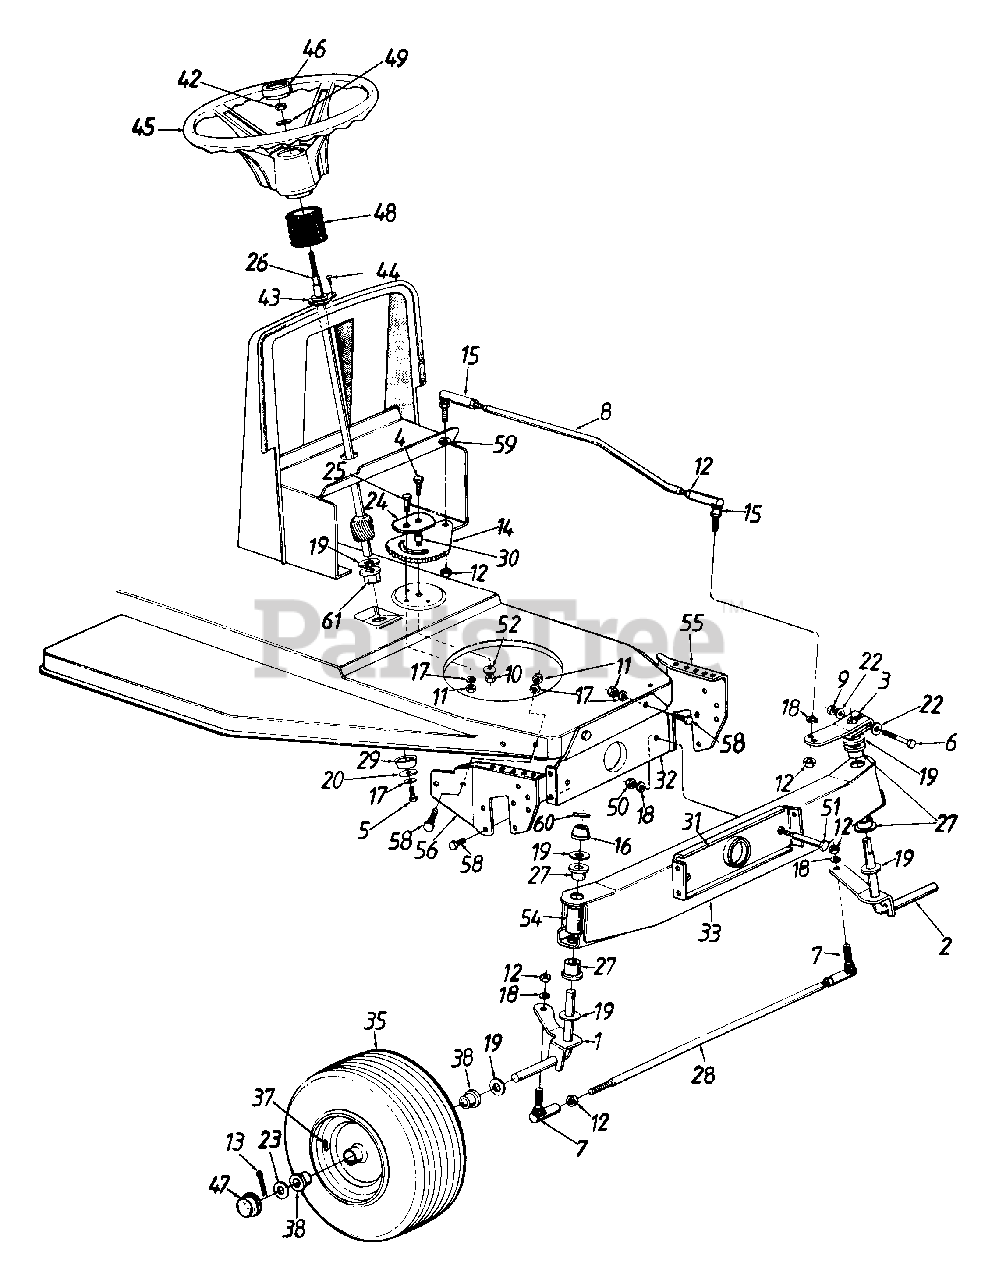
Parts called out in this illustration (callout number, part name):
1	Front Axle Ass'y.- R.H. w/Bronze Bearing
2	Front Axle Ass'y.- L.H. w/Plastic and Ball Bearing
3	Steering Arm
4	Hex Bolt 3/8-24 x 1" Lg.
5	Hex Bolt 5/16-18 x .62"
6	Hex Bolt 5/16-24 x 2" Lg.
7	Ball Joint 3/8-24 Thd.
8	Steering Drag Link
9	Hex L-Nut 5/16-24 Thd.
10	Hex Nut 3/8-24 Thd.
11	Hex Nut 5/16-18 Thd.
12	Hex Jam Nut, 3/8-24 Thd.
13	Cotter Pin 1/8 Dia.
14	Steering Gear Segment
15	Drag Link Ball Joint 3/8-24 Thd.
16	Push Cap
17	L-Wash. 5/16" I.D.
18	L-Wash. 3/8" I.D.
19	Fl-Wash..64" I.D. x 1.24"
20	Fl-Wash..340" I.D. x 1.125"
22	Spr. Wash..32" I.D. x .62"
23	Fl-Wash..635" I.D. x 1.585"
24	Retainer Plate
25	Shld. Bolt .437" Dia. x .350"
26	Steering Shaft
27	Hex Flange Brg..632" I.D.
28	Tie Rod 20" Lg.
29	Spacer .985" I.D.
30	Spacer .380" I.D.
37	Air Valve 15" x 16" w/Plastic, Bronze and Ball Bearing
38	Bearing 15" x 16" w/Plastic Bearing
42	Hex L-Nut 5/16-24 Thd.
43	Steering Column Brg.
44	Cr-Sunk Scr. #10 x 5/8" Lg.
45	Steering Wheel
46	Steering Wheel Cap
47	Hub Cap
48	Bellow Steering Column
49	Bell-Wash..345" I.D. x .88"
50	Hex Nut 3/8-16 Thd.
51	Shld. Bolt 1/2" Dia. x 2.04"
52	Bell-Wash..39" x 1.38" O.D.
54	Plastic Tube
55	Pivot Bar Side Plate - L.H.
56	Pivot Bar Side Plate - R.H.
58	Hex Wash. Tap Scr. 5/16-18 x .62" Lg.
59	L-Wash. 3/8" I.D. (H.D.)
60	Roll Pin
61	Hex Flange Brg..634" Dia.
